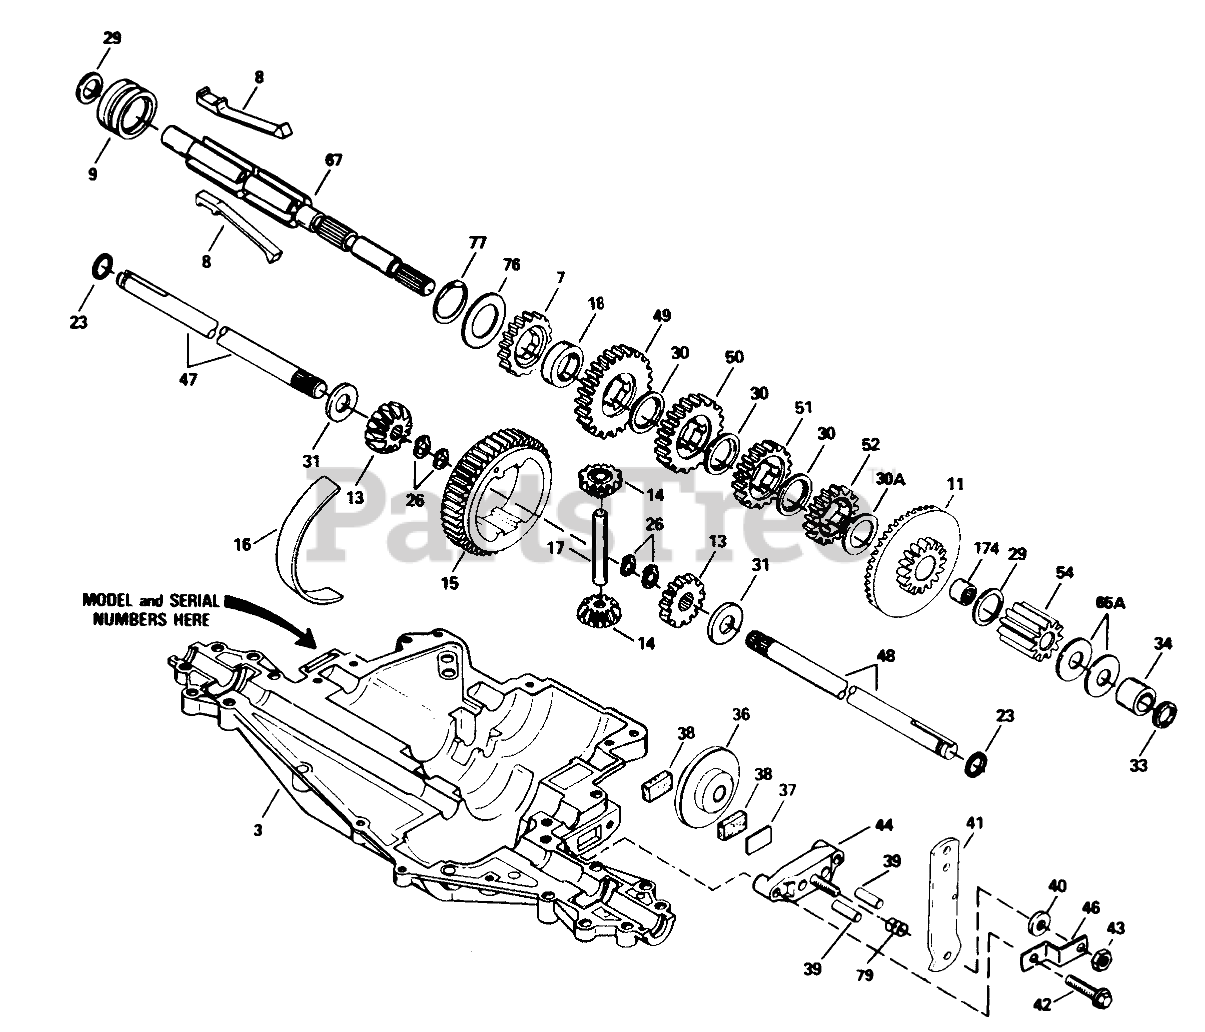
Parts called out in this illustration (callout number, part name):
3	Transaxle Case
7	Gear-Spur (22 teeth)
8	Shift Key
9	Shift Collar
11	Bevel Gear & Bearing (44/16 Teeth)(Incl. Ref. #174)
13	Gear Bevel
14	Gear Pinion
15	Gear-Ring
16	Bearing Strip
17	Drive Pin
18	Neutral Spacer
23	Ring-Seal
26	Retaining Ring (pkg of 2)
29	Washer
30	Washer
30A	Washer
31	Washer
33	O-Ring
34	Bushing
36	Brake Disk
37	Brake Pad Plate
38	Brake Pad
39	Dowel Pin
40	Washer
41	Brake Lever
42	Ring Set (.020 O S)
43	Locknut
44	Nozzle-Carburetor
46	Bracket
47	Axle (16-13/16" Ig.)
48	Axle (11-5/8" lg.)(Incl. Ref. #26)
49	Gear-Spur, 35 Teeth
50	Gear-Spur 27 Teeth
51	Spur Gear (19 Teeth)
52	Gear-Spur 20 teeth
54	Spur Gear (11 Teeth)
65A	Washer
67	Shifter & Brake Shaft
76	Washer
77	Inverted Retaining Ring
79	Piston ASM (.020 O S)
174	Needle Bearing
